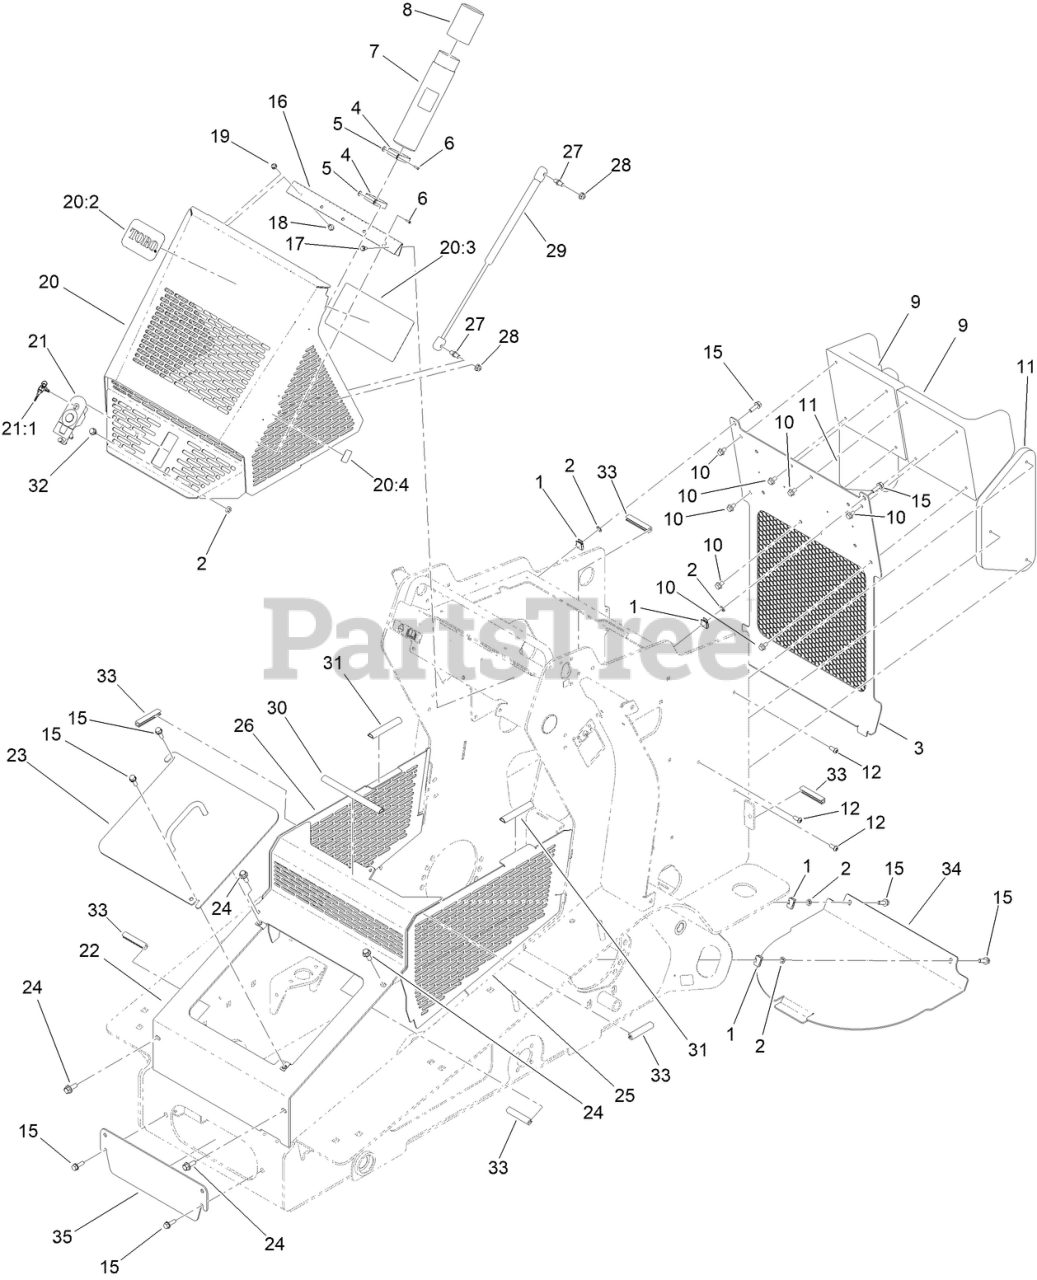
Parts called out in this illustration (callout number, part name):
1	NUT-CLIP, U
2	RING-RETAINING, BOLT
3	COVER-REAR [BLK-TXT]
4	CLAMP-R
5	WASHER-BACK
6	RIVET-POP
7	TUBE-MANUAL
8	CAP-HOUSING
9	PAD-OPERATOR
10	SCREW-HHF
11	PAD-OPERATOR, KNEE
12	SCREW-HSBH
15	SCREW-HHF
16	HINGE-HOOD
17	SCREW-HWH
18	SCREW-HHF
19	NUT-HF
20	HOOD ASM
20:2	DECAL-TORO LOGO
20:3	DECAL-SERVICE INTERVAL
20:4	DECAL-OPERATOR MANUAL
21	LATCH-COMPRESSION, LOCKING
21:1	KEYS-LATCH
22	PANEL-COVER, FRONT
23	COVER-ACCESS, BATTERY [BLK-TXT]
24	SCREW-HHF
25	COVER-SIDE, LH
26	COVER-SIDE, RH
27	STUD-BALL
28	NUT-HF, NI
29	SPRING-GAS
30	SEAL-BULB
31	SEAL-BULB
32	SCREW
34	COVER-ACCESS, BOTTOM
35	COVER-ACCESS, FRONT
